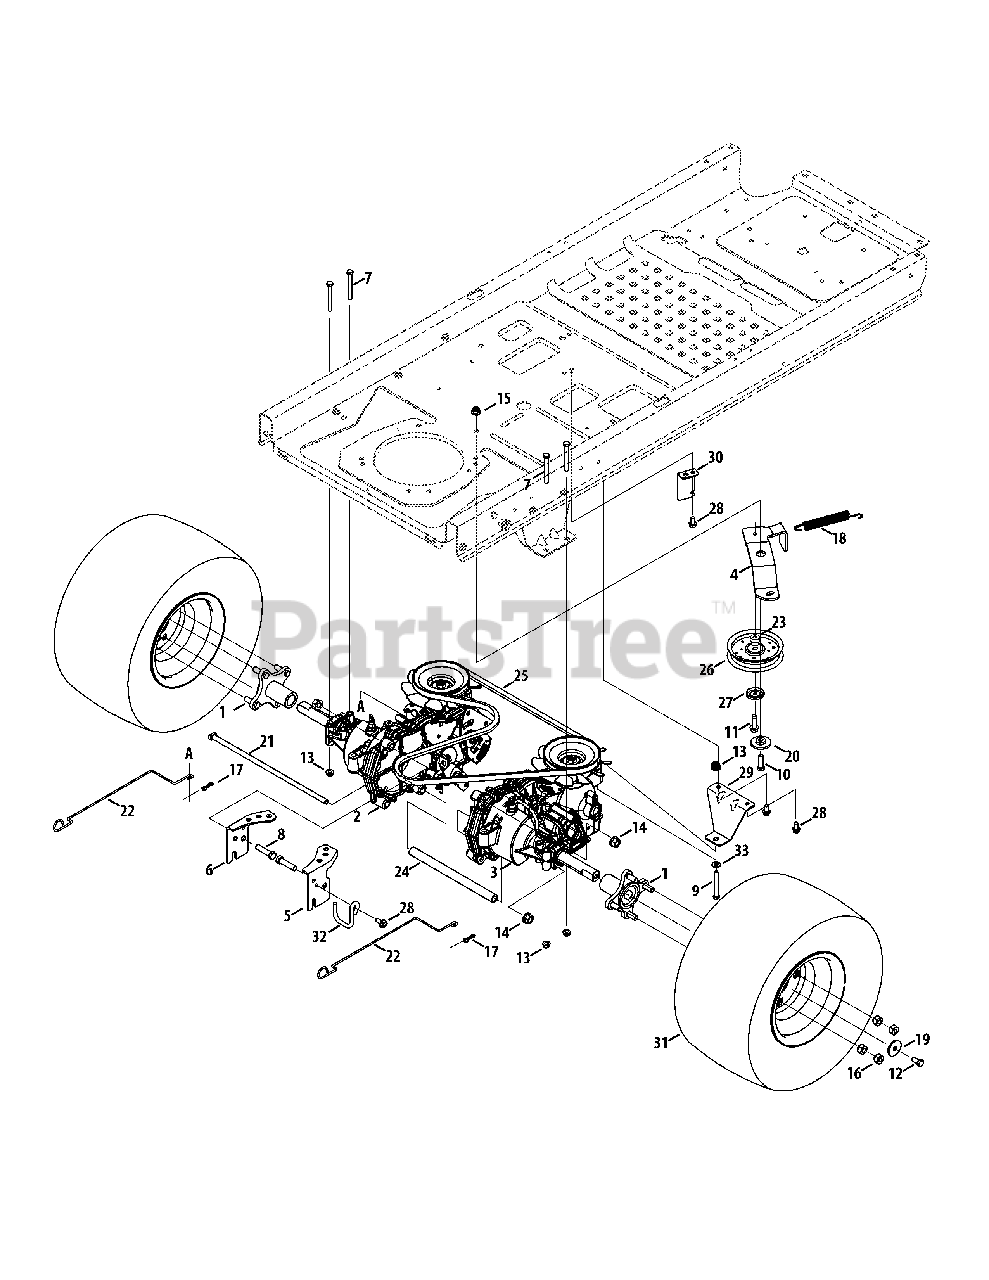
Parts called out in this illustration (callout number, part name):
1	Wheel Hub Assembly
2	LH Transmission
3	RH Transmission
4	Hydro idler Bracket
5	RH transmission Mount Bracket
6	LH transmission Mount Bracket
7	Hex Screw, 5/16-18 x 2.75
8	Hex Screw, 7/16-20 x 1.750
9	Hex Screw, 5/16-18 x 2.25
10	Hex Screw, 3/8-16 x 1.00
11	Hex Washer Screw, 3/8-16 x 1.250
12	Hex Screw, 3/8-16 x .750
13	Flange Lock Nut, 5/16-18
14	Flange Lock Nut, 7/16-20
15	Jam Lock Nut, 3/8-16
16	Lug Nut, 7/16-14
17	Cotter Pin
18	Extension Spring.75 x 5.365
19	Flat Washer, .390 x 1.500 x .134
20	Shoulder Spacer, .8840 x .190
21	Rod, .405 x 14.0
22	Bypass Rod
23	Toggle Lock Shoulder Spacer
24	Tube, .51 x .75 x 10.2
26	Idler Pulley, 4.25
27	Pulley Cap
28	Hex Washer Screw, 5/16-18 x .750
29	Transmission Mount Bracket
30	Spring Mount Bracket
31	Wheel Assembly, 18 x 9.5-8
32	Clutch Keeper Rod
33	Flat Washer, .330 x .630 x .064
